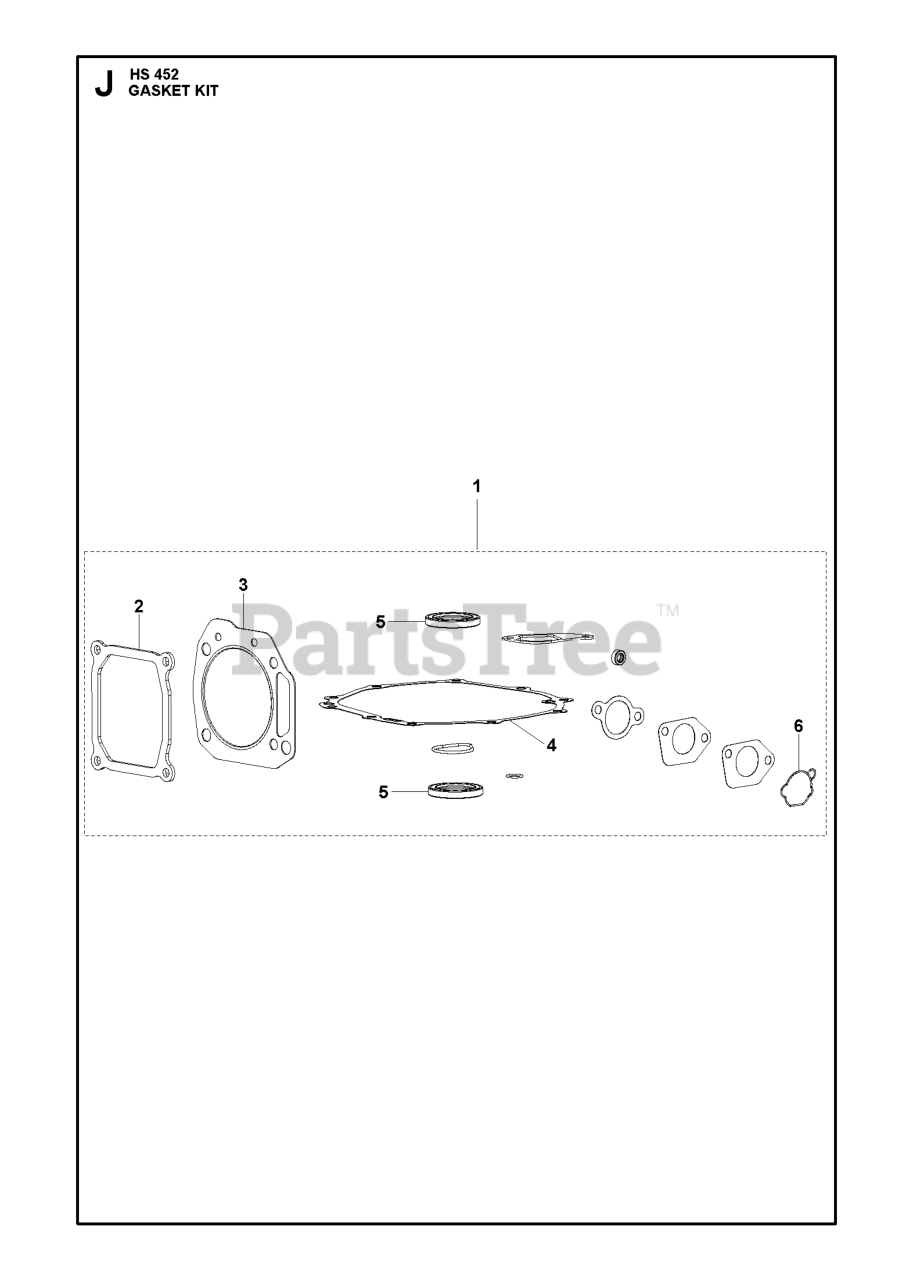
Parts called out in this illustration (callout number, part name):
1	SERVICE KIT GASKET AND SEAL KI
2	GASKET CYLINDER HEAD COVER GAS
3	GASKET CYLINDER HEAD GASKET
4	GASKET CRANKCASE COVER GASKET
5	SEAL OIL SEAL
6	GASKET CARBURETTOR GASKET
